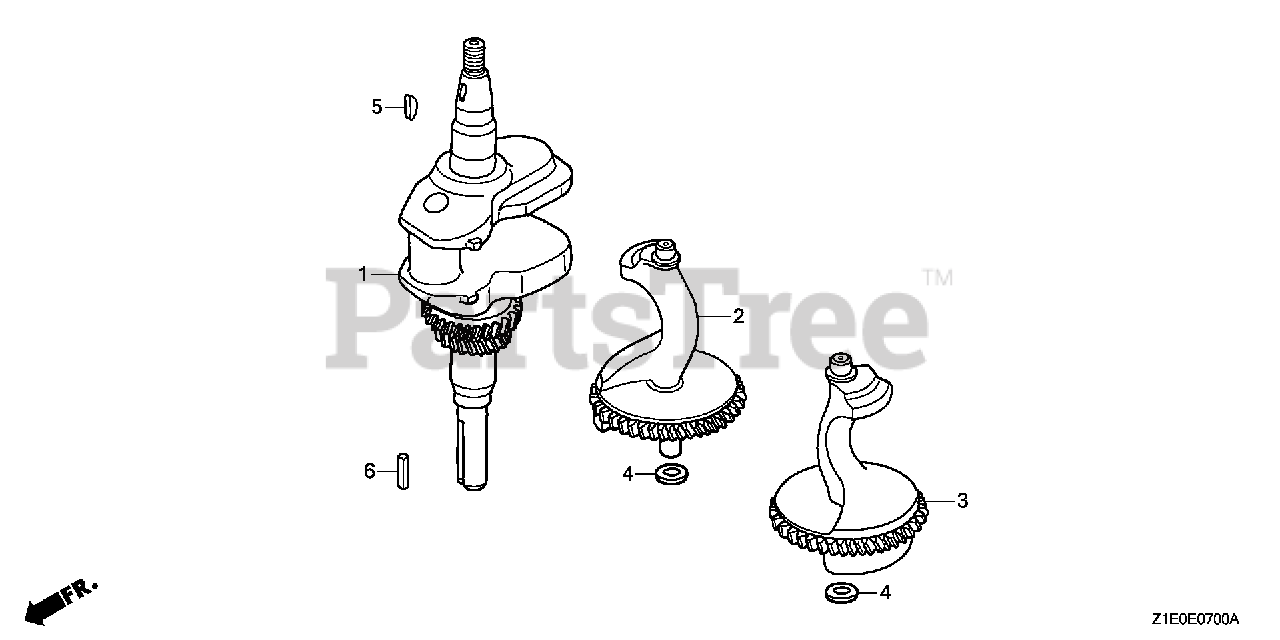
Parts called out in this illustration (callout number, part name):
1	CRANKSHAFT
2	WEIGHT A, BALANCER
3	WEIGHT B, BALANCER
4	WASHER, THRUST (14MM)
5	KEY, SPECIAL WOODRUFF (25X18)
